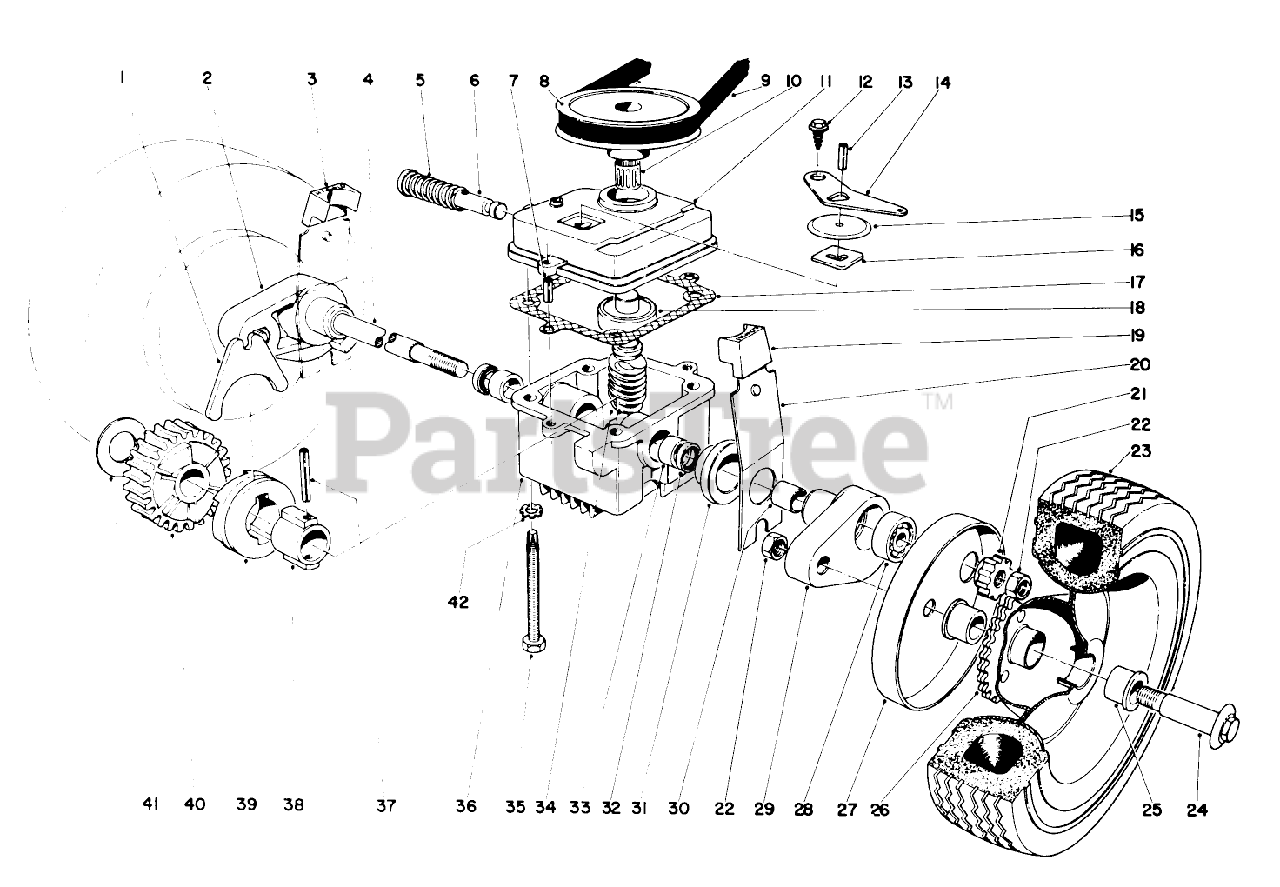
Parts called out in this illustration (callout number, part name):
1	SHIFTER FORK
4	DRIVE SHAFT
5	SPRING
7	3/16 X 1/2 ROLL PIN
9	BELT-V
10	Tolerance Ring
13	PIN-ROLL
14	SHIFTER ARM
15	TRANS DUST COVER
16	LATCH PLATE
17	GASKET
19	ARM KNOB
21	PINION GEAR
27	WHEEL COVER
28	.375 RPP BALL BEARING
29	LH PIVOT ARM & BSHG
30	BUSHING
33	Bushing
34	Worm Shaft
38	SLEEVE
40	Worm Gear
41	THRUST WASHER
42	WASHER-LOCK/EXT
